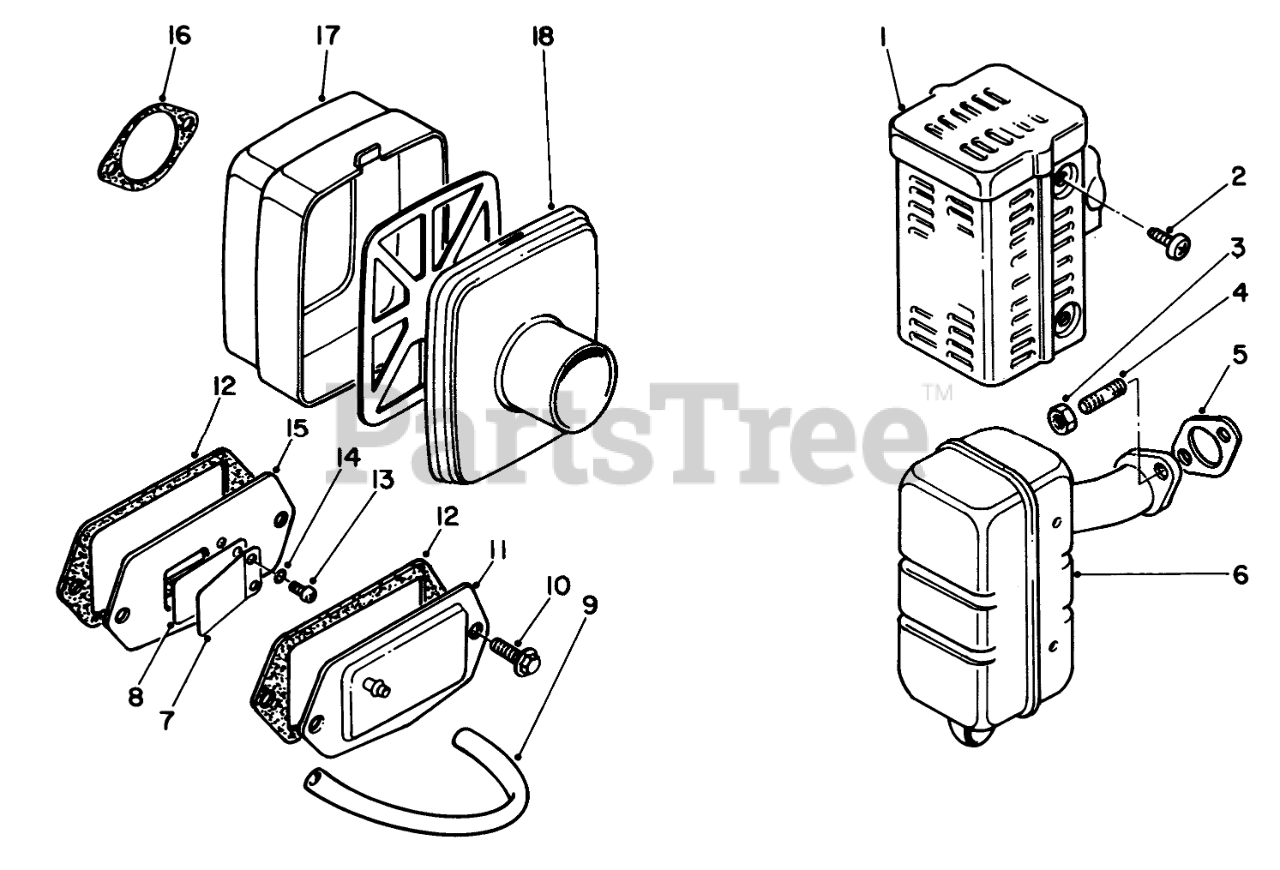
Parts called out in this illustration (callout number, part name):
1	Cover-Muffler
2	Screw-Round Phillips Hd.
4	Stud Bolt
5	Gasket-Exhaust
6	Muffler
7	Stopper
8	Valve-Reed
11	Cap-Breather
12	Gasket
13	Screw
14	Lockwasher
15	Reed Valve Assembly(Incl. Ref. #7, 8, 13 & 14)
16	GASKET-AIR CLEANER
17	Air Cleaner Assembly(Incl. Ref. #18)
